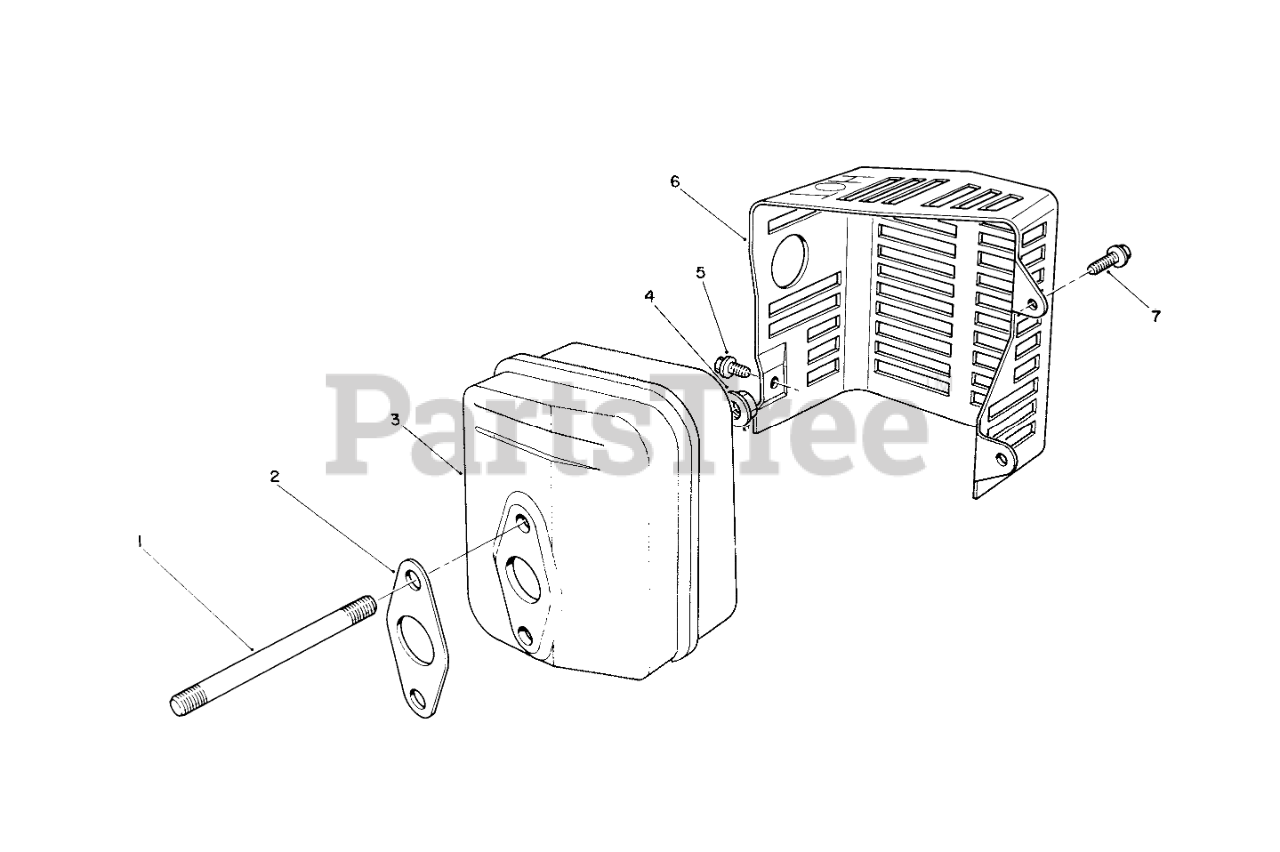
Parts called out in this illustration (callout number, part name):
2	GASKET
3	MUFFLER
5	SCREW
6	COVER
